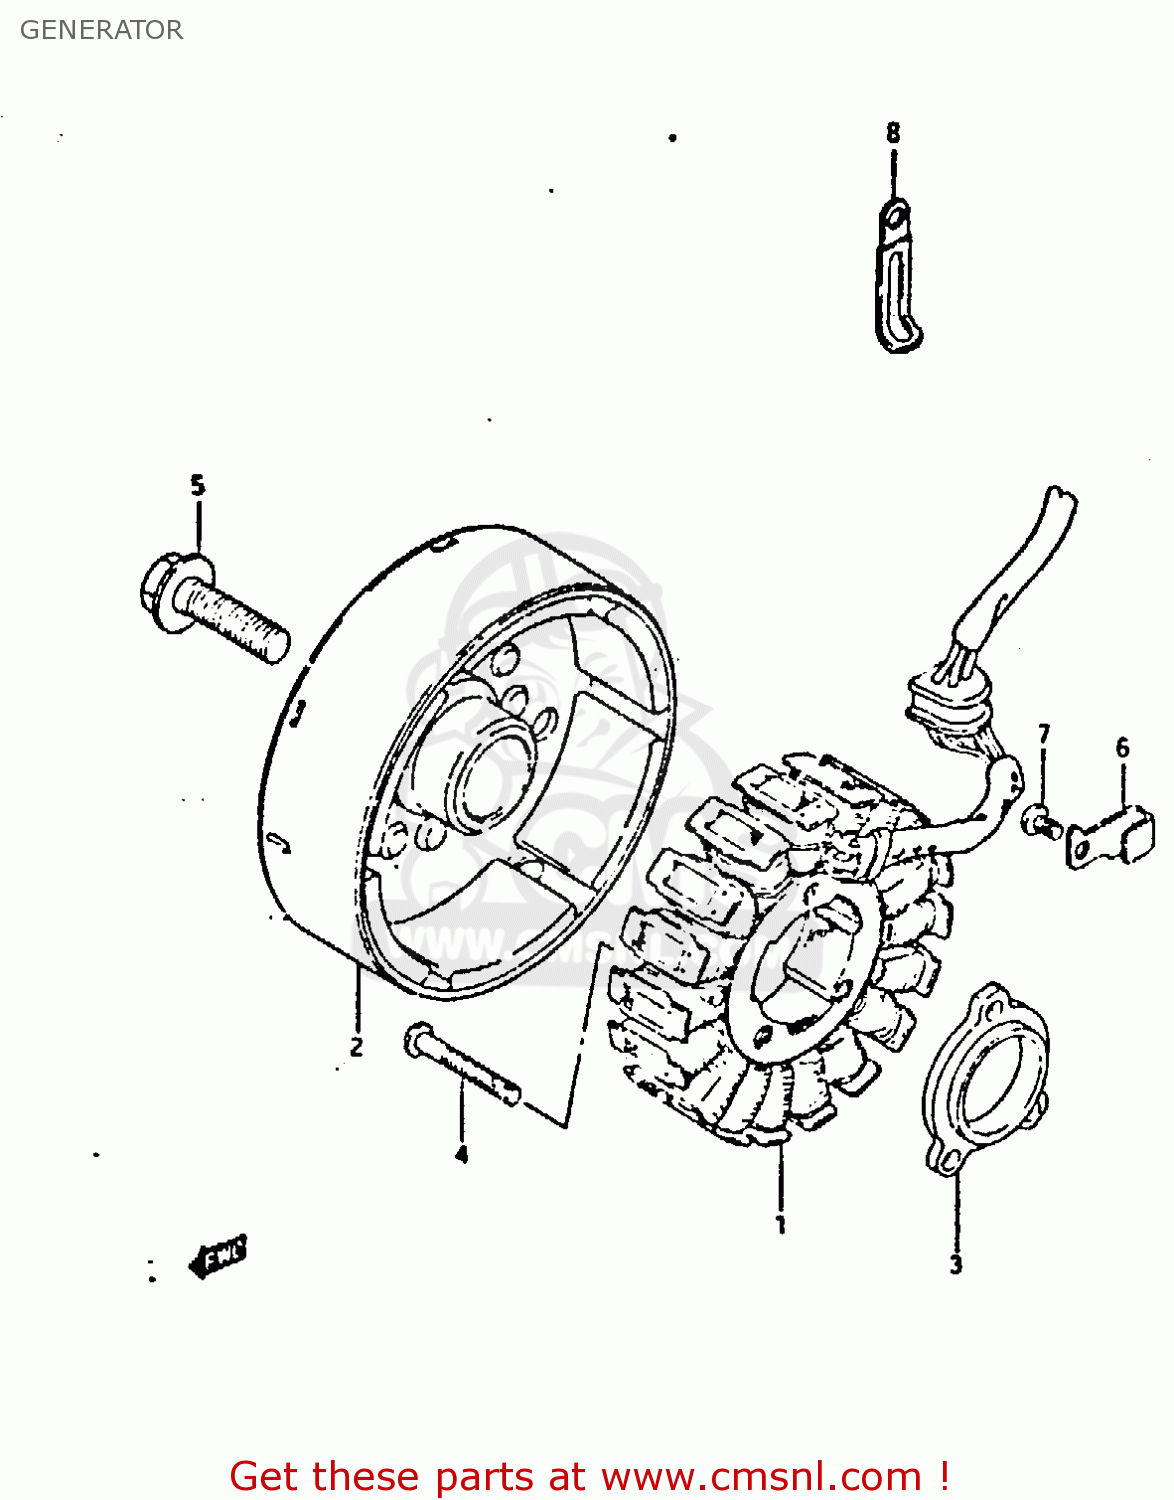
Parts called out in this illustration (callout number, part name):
1	STATOR ASSEMBLY
2	ROTOR
3	SPACER,GENERATOR STATOR
4	SCREW
5	BOLT(12X40)
6	CLAMP,GENERATOR LEAD WIRE
7	SCREW
8	CLAMP
